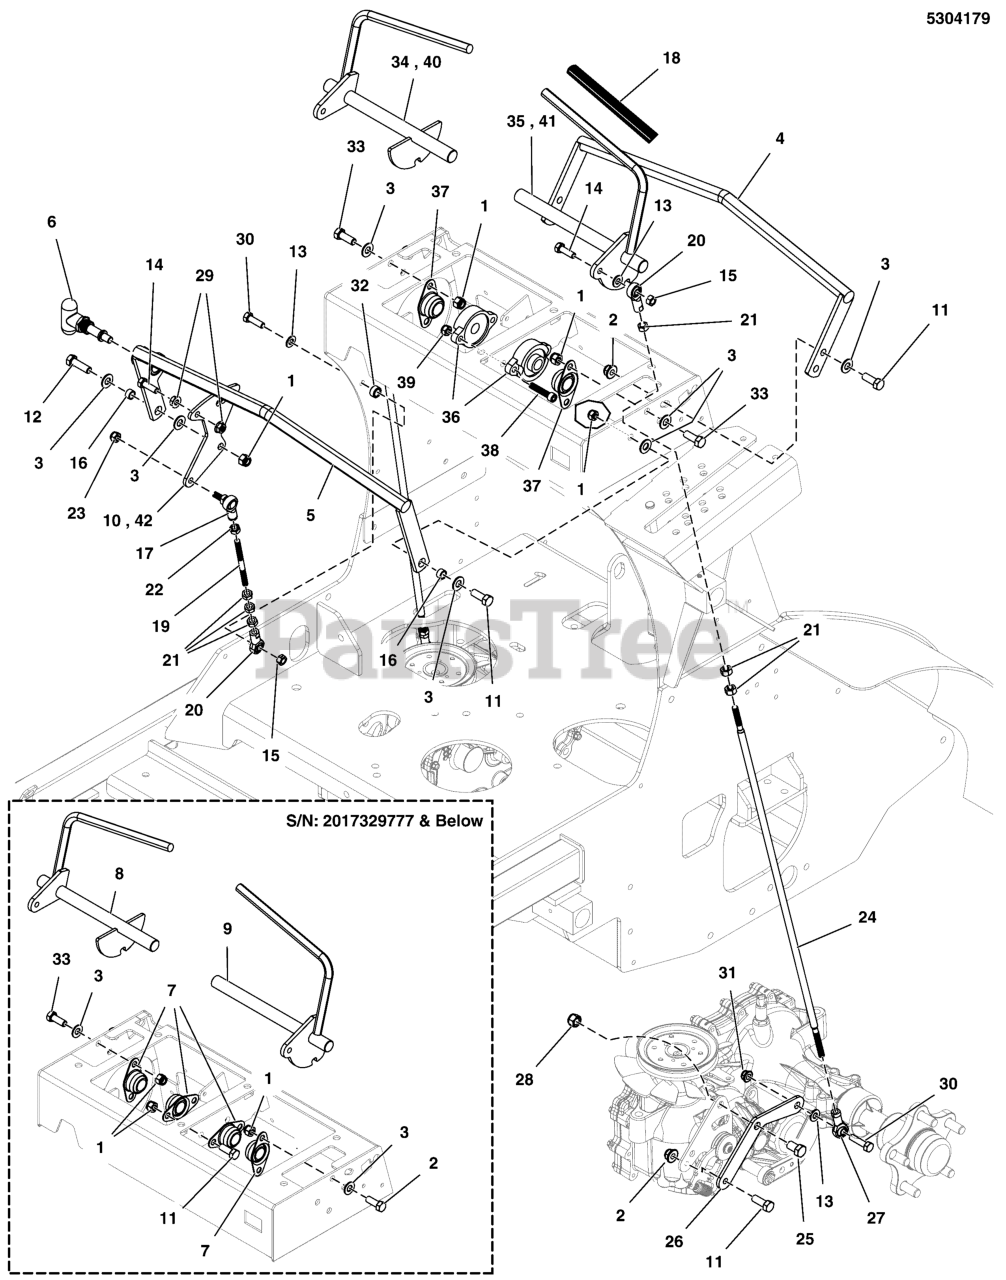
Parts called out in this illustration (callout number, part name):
1	NUT, 3/8-16 HEX NYLON LOCK
2	NUT, 3/8 - 16 HEX NYLOCK FLANGE
3	WASHER, 3/8 SAE
4	WELD, REAR HANDLE, STAND ON - BLK
5	WELD, FRONT HANDLE, STAND ON - BLK
6	PULL PIN, 3/8" DIA X 9/16" STROKE
7	BEARING, BRONZE FLANGE, 3/4"
8	WELD, HANDLE MOTION CONTROL RH - BLK
9	WELD, HANDLE MOTION CONTROL LH - BLK
10	PLATE, SPEED ADJUSTMENT, STAND ON - BLK
11	BOLT, 3/8-16 X 1" GD5 CZ
12	BOLT, 3/8-16 X 1-1/4" GD5 CZ
13	WASHER, 5/16" SAE
14	BOLT, 5/16-18 X 1" GRD5 YZ
15	NUT, 5/16-1/8, HEX, CNTR LK, ZINC PHOS/OIL
16	SPACER, .38 X .50 X .27, CZ
17	BALL JOINT, 5/16-24 LH FEMALE W/STUD, BR
18	GRIP, FOAM, .48 x 10 x .125 Black
19	ROD, 5/16-24 X 4.25, CZ
20	BALL JOINT 5/16-24 RH FEMALE BRONZE RACE
21	NUT, Hex, 5/16-24
22	NUT, 5/16-24 HEX, LH
23	NUT, 5/16-24 HEX NYLON LOCK
24	ROD, MOTION CONTROL, STAND-ON
25	BOLT, 7/16-14 X 3/4, GD 5 YZ
26	PLATE, CONTROL MOUNT - BLK
27	BALL JOINT 5/16-24 LH FEMALE BRONZE RACE
28	NUT, 7/16-14 HEX TOP LOCK
29	NUT, 5/16-18 HEX SERRATED FLANGE (SMALL)
30	BOLT, 5/16-18 X 1-1/4" GD5 YZ
31	NUT, 5/16-18 HEX NYLOCK FLANGE NUT
32	SPACER, .33 X .50 X .25, PM, CZ
33	BOLT, 3/8-16 X 3/4" GD5 CZ
34	WELD, CONTROL HANDLE, RH, SRS
35	WELD, CONTROL HANDLE, LH, SRS
36	BEARING-FLANGE, 5/8
37	BEARING, BRONZE, FLANGED, 5/8", FLB10
38	SCREW, SOC HD, 5/16-18 X 1-1/2, BLK
39	NUT, Hex, Nylon Locking, 5/16-18
40	WELD, CONTROL HANDLE, RH, SRS Z2 - BLK
41	WELD, CONTROL HANDLE, LH, SRS Z2 - BLK
42	PLATE, SPEED ADJUSTMENT, SRS - BLK
